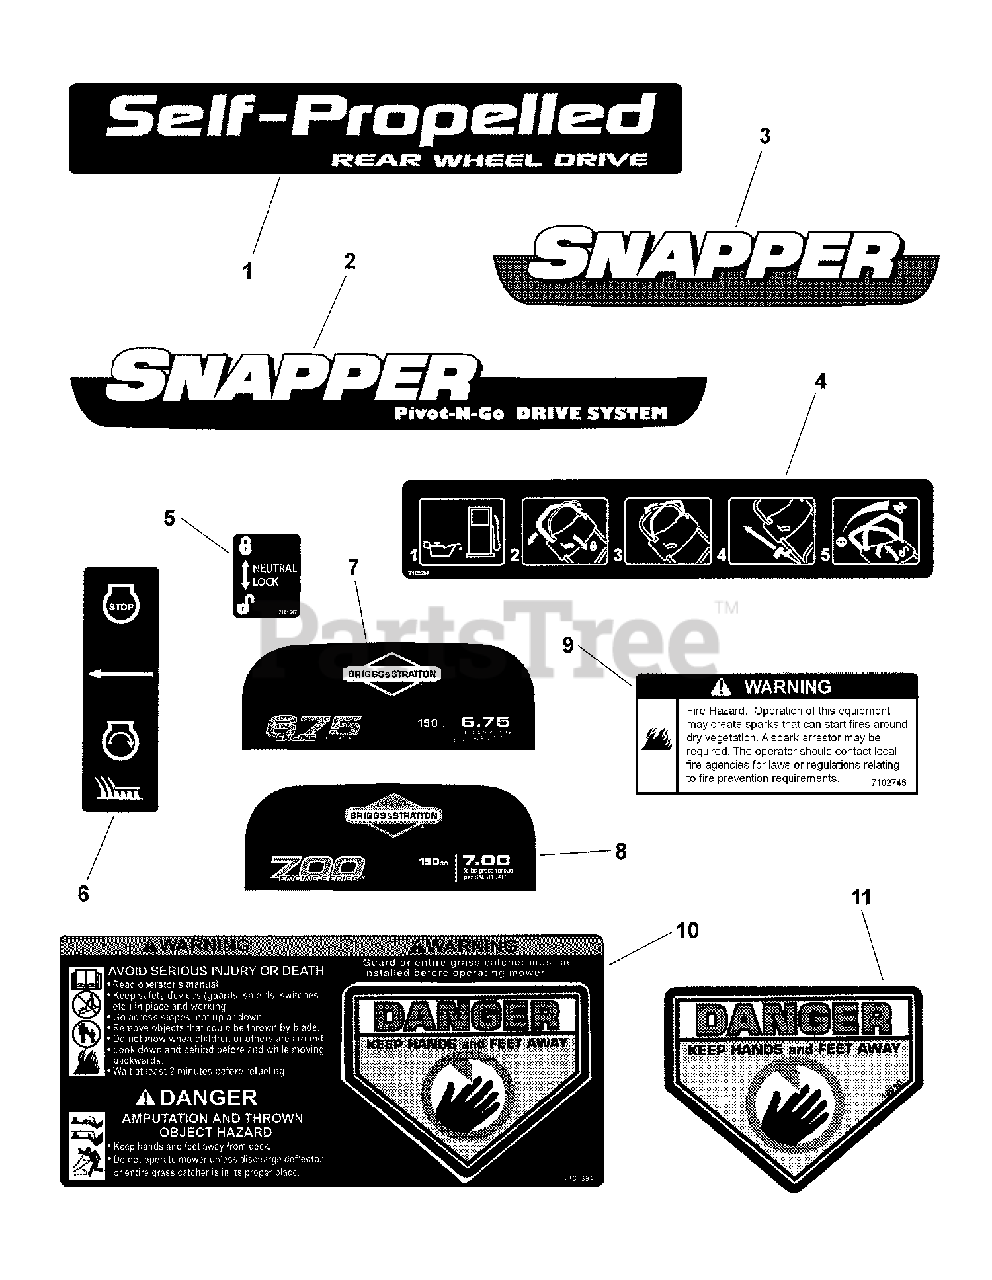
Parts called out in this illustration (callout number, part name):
1	DECAL, Front Cover, 21" RD, Snapper
2	DECAL, Pivot-N-Go
3	DECAL, Briggs Engine, Snapper
4	DECAL, Pivot Handle, Snapper
5	DECAL, Neutral Lock
6	DECAL, OPC Bail International Symbol
7	DECAL, Briggs Engine, 675 Series
8	DECAL, Briggs Engine, 700 Series
9	DECAL, Spark Arrestor
10	DECAL, Warning, Rear Discharge Door
11	DECAL, Danger, Cut Finger
